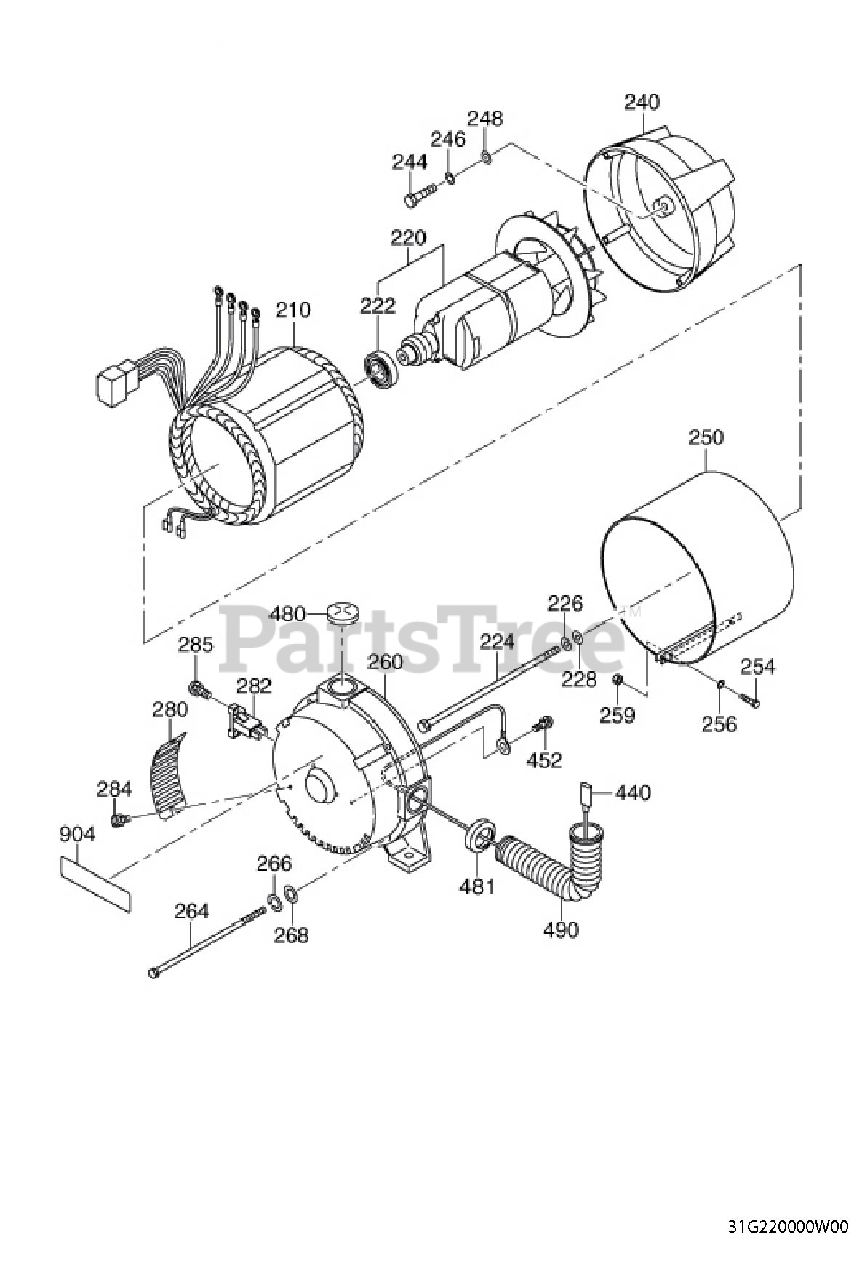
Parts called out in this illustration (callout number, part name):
224	THROUGH BOLT
226	SPRING WASHER
228	WASHER
240	FRONT BRACKET
244	BOLT
246	SPRING WASHER
248	WASHER
254	BOLT
264	THROUGH BOLT
266	SPRING WASHER
268	WASHER
282	BRUSH HOLDER CP
284	SCREW and WASHER AY
285	SCREW and WASHER AY
452	SCREW
